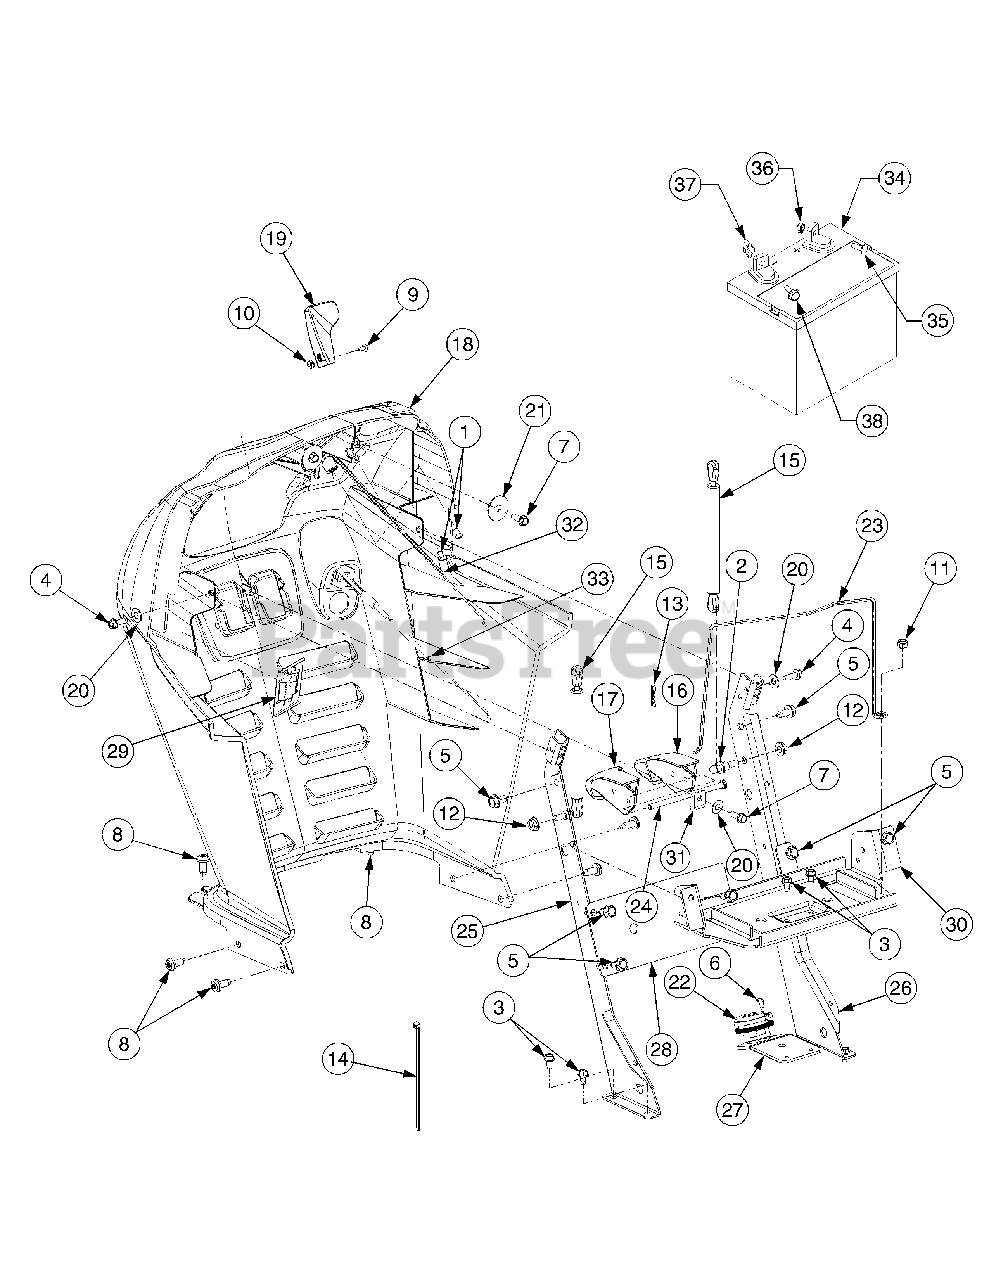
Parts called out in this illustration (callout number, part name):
1	Screw, #10-24 X .375
2	Screw, Ball, 5/16-18
3	Screw, Self-tapping, 1/4-20, 0.500
4	Screw, Hx. Wash. Hd, Tapp. 1/4-20 x .75
5	Screw, Hx. Wash. Hd, Tapp, 5/16-12 x .75
6	Screw, Oval Cntrsnk, #10-16 x .625
7	Screw, 1/4-15, 0.750
8	Screw, Torx Hd. Tapp. 5/16-18 x .75
9	Screw, Truss Mach., #8-32 x .375
10	Nut, Hex, #8-32 GrA
11	Nut, Hex Insert Lock, 1/4-20 GR8
12	Nut, Hex Flange Lock, 5/16-18 GR5
13	Internal Cotter Pin, .072 x 1.13
14	Cable Tie
15	Cylinder, Gas
16	Lever, Dash, Brake
17	Lever, Dash, Cruise
18	Dash
18	Graphic, Dash Insert
19	Knob, Throttle Control
20	Washer, Flat, .28 x .74 x .063
21	Washer, Flat, .33 x 1.25 x .06 HT
22	Bearing, Steering Column
24	Rod, .25 x 4.55
32	Cable, Throttle, 38.0 Lg
33	Cable, Choke, 40.5 Lg.
34	Battery, 235 CCA, Dry
35	Screw, Carriage, 1/4-20, .75,
36	Nut, Hex, 1/4-20, Sems
37	Nut, Wing, 1/4-20
38	Screw, Shoulder, 1/4-20, .25 x .15
